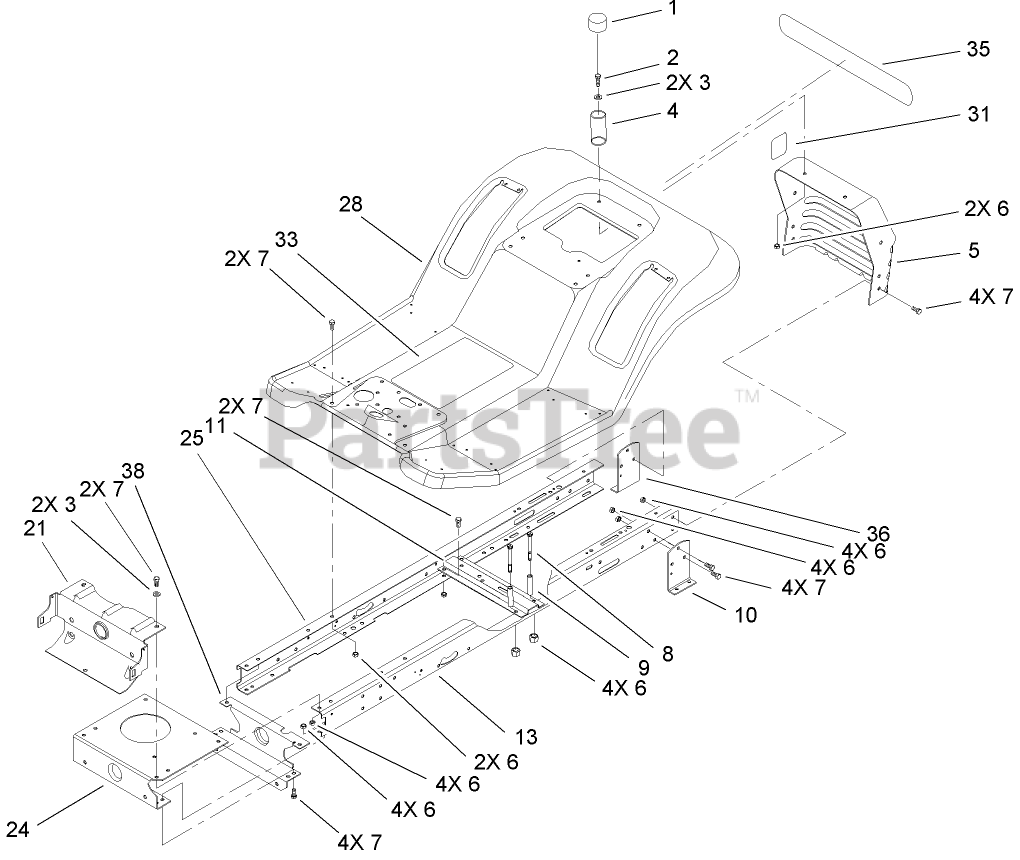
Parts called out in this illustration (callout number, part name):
1	CAP-PROTECTOR
2	SCREW-HH
3	WASHER-PLAIN
4	SPRING-COMPRESSION
5	SUPPORT-SEAT/REAR HITCH
6	NUT-LOCK, NI
7	SCREW-HH
8	SCREW-HH
9	SPACER
10	BRACKET-MOUNTING, LH TRANSAXLE
11	BRACKET-IDLER PIVOT
13	RAIL-FRAME, LH
21	SUPPORT-AXLE, FRONT
24	PLATE-MOUNTING, ENGINE
25	RAIL-FRAME, RH
28	REAR BODY ASM
31	DECAL-VALVE, DUMP
33	DECAL-INSTRUCTION
35	DECAL-REAR FENDER, LAWN TRACTORS
36	BRACKET-MOUNTING, RH TRANSAXLE
38	SUPPORT-REAR
